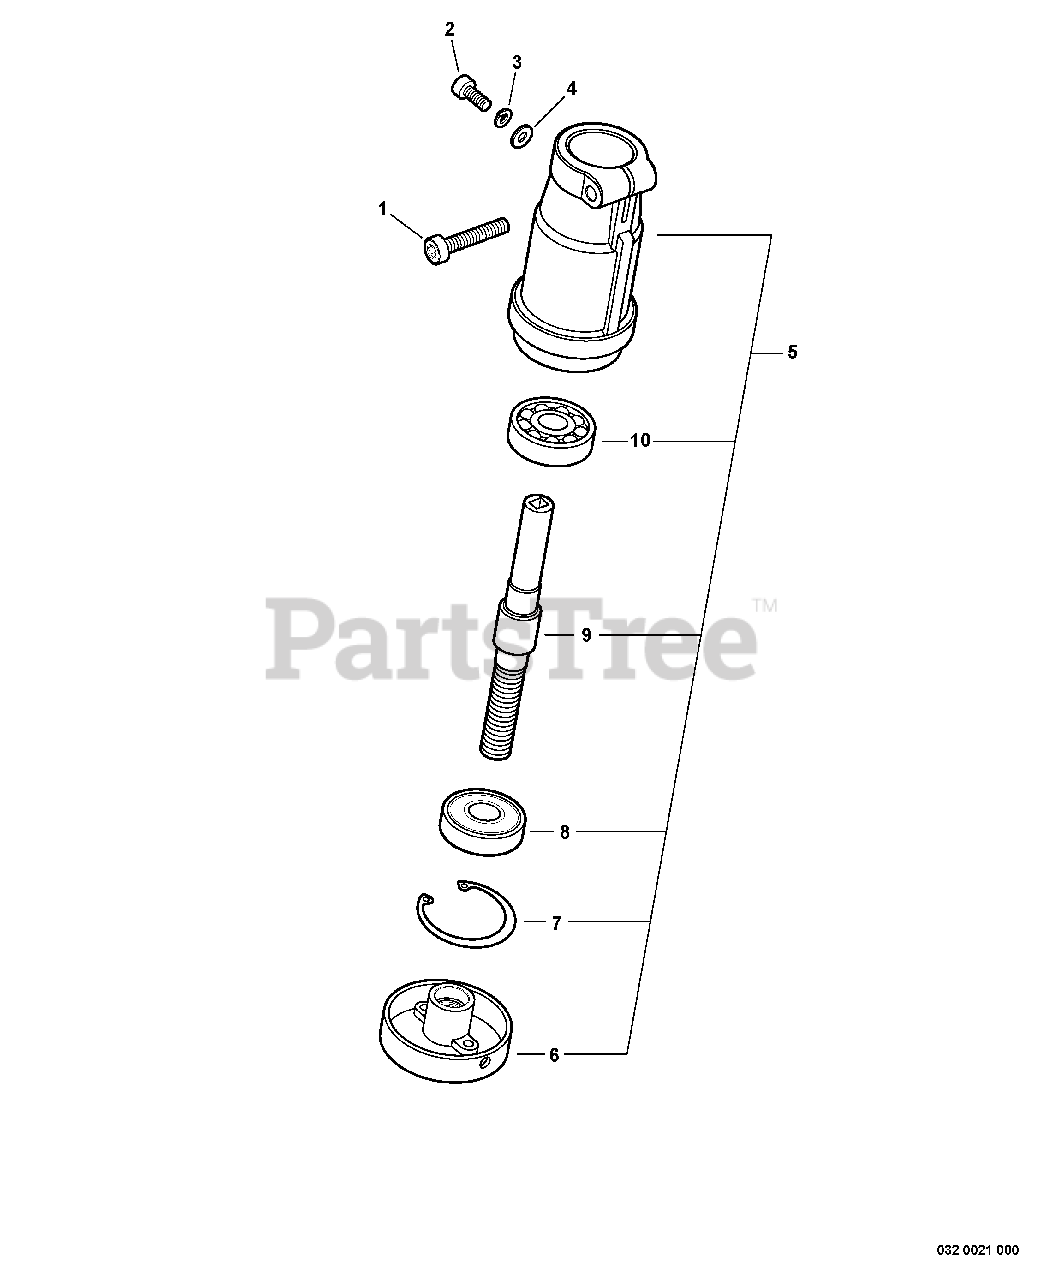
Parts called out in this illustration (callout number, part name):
1	SCREW - 5X25
2	SCREW - 4X10
3	LOCKWASHER - 4
4	WASHER - 4
5	GEAR CASE ASSY
6	ADAPTOR, BLADE - UPPER
7	RING, RETAINING - 30
8	BEARING, BALL - 6200
9	GEAR - SHAFT
10	BEARING, BALL - 6200
